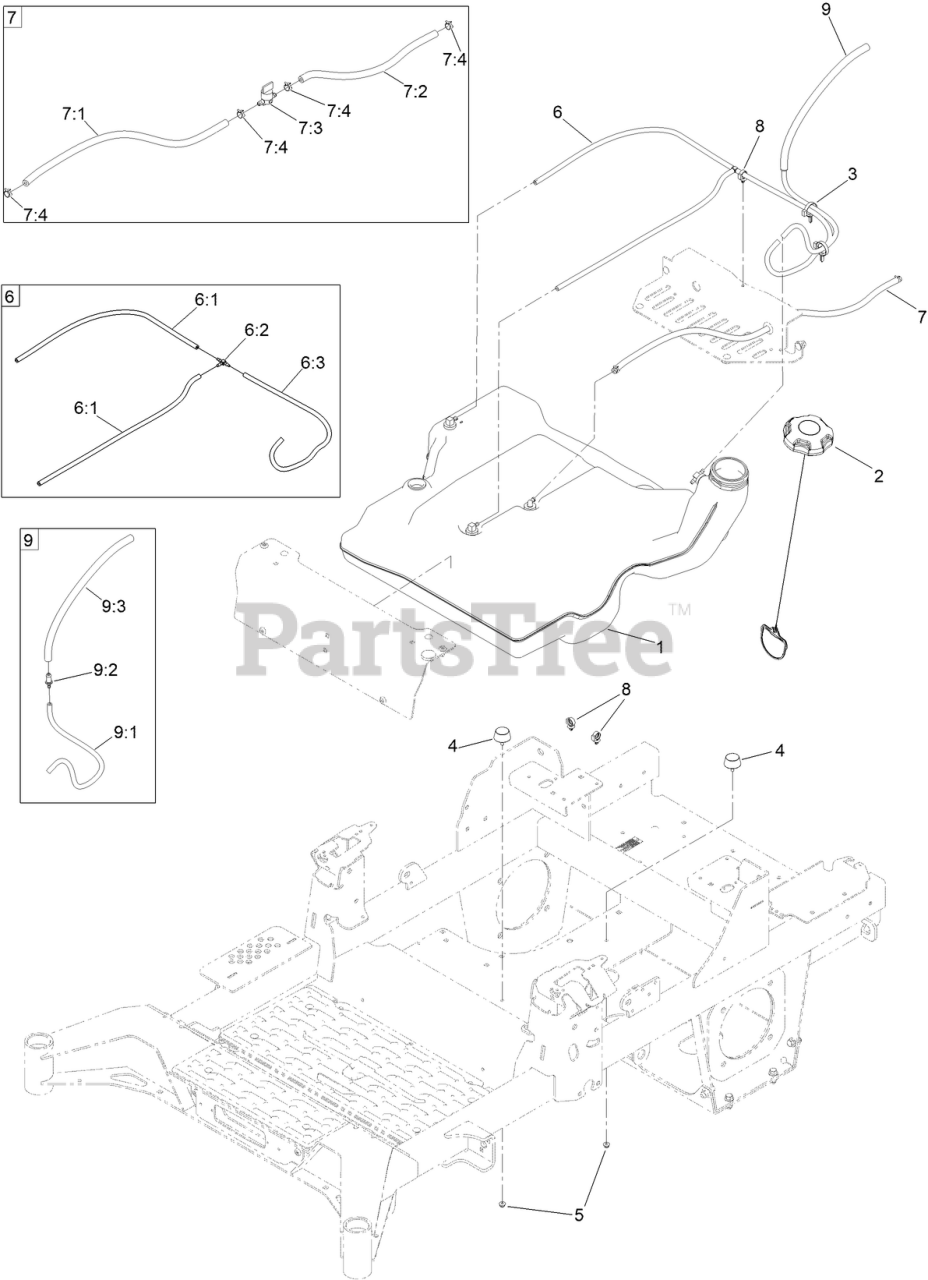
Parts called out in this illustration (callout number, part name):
1	FUEL TANK ASM
2	CAP-FUEL, RATCHETING
3	CLAMP-HOSE
4	BUMPER
5	NUT-HF
6	VENT HOSE ASM
6:1	HOSE-VENT
6:2	FITTING-TEE
6:3	HOSE-FUEL
7	FUEL HOSE ASM
7:1	HOSE-FUEL
7:2	HOSE-FUEL
7:3	VALVE-FUEL
7:4	CLAMP-HOSE
9	ASM-FUEL VENT
9:1	HOSE-VENT
9:2	FITTING-ORIFICE, STRAIGHT
9:3	HOSE-FUEL
